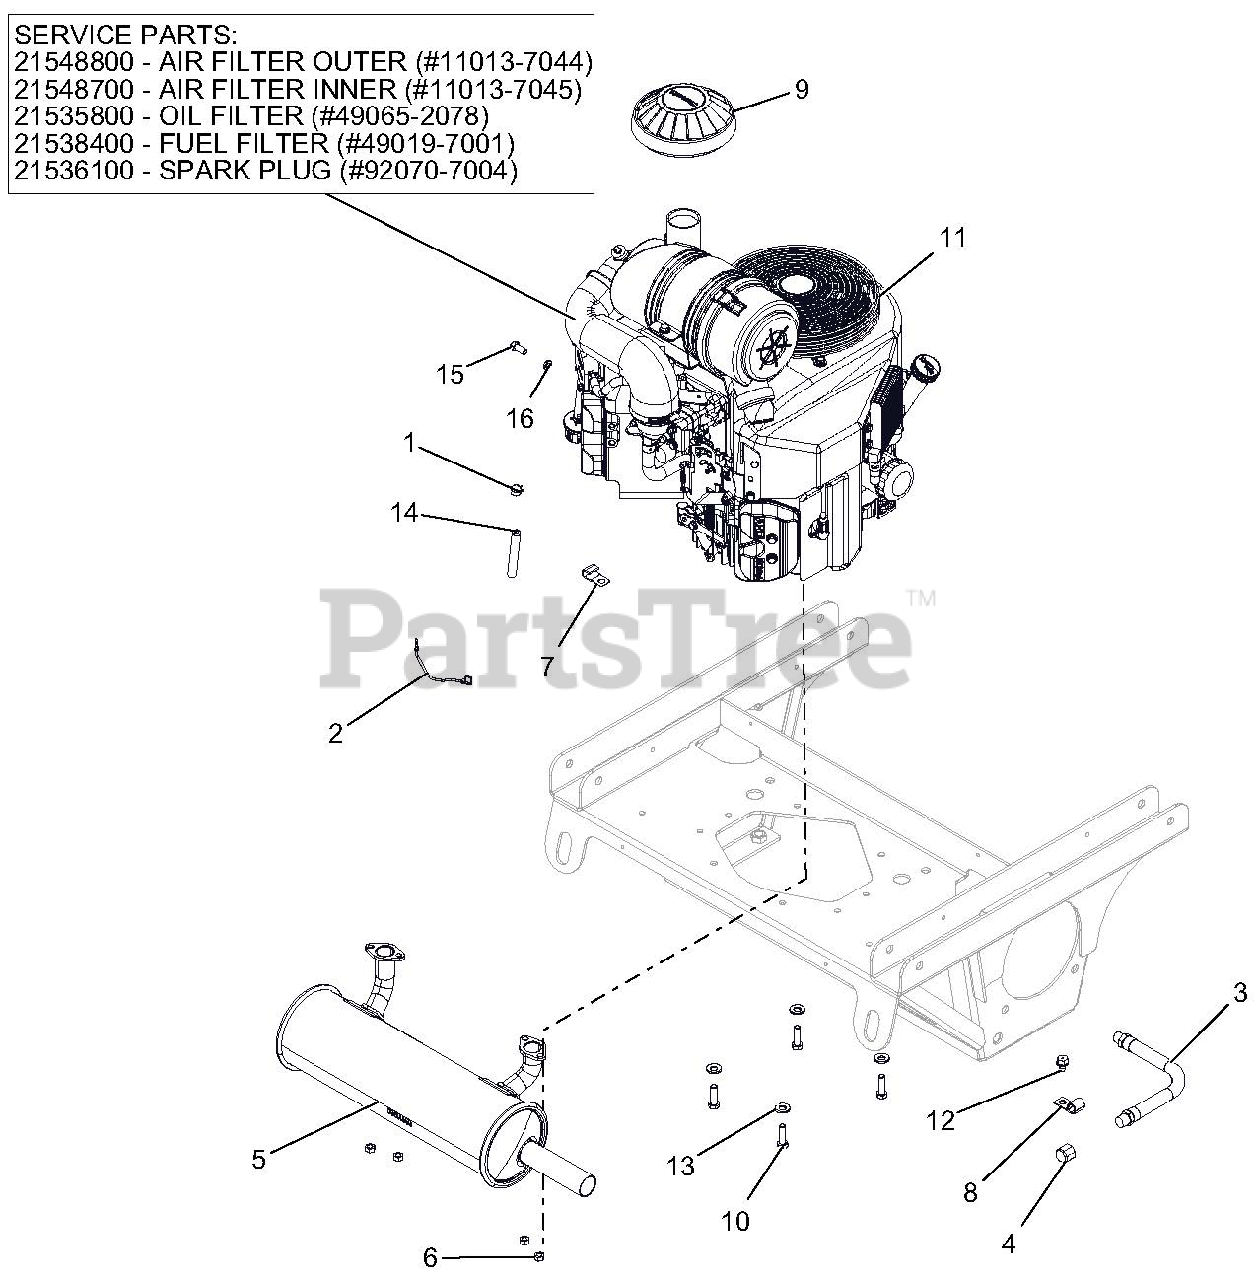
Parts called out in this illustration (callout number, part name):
1	CLAMP, FUEL LINE
2	LEAD - STARTER SOLENOID
3	HOSE, HYD .38-11-0K M6N0-M6NO
4	PIPE, CAP 3/8 NPT FEMALE
5	MUFFLER, 27-31 FX KAW
6	NUT-LK-TOP M8-1.25 YWZC
7	CLAMP, J
9	CAP, AIR CLEANER INTAKE (2")
10	BLT-HEX .38-16X1.25 GR5 YWZC NYTORQ
11	ENGINE, KAWASAKI FX850
11	AIR FILTER OUTER (#11013-7044)
11	AIR FILTER INNER (#11013-7045)
11	OIL FILTER (#49065-2078)
11	FUEL FILTER (#49019-7001)
11	SPARK PLUG (#92070-7004)
12	SCR-TAP .38-16X.50 HWH TR YWZ
13	WSHR, 3/8" SPRING DISC
14	.25 LOW-PERM GAS HOSE 18.00" LG - Valve to engine
15	@BLT-HEX M8-1.25X20 YWZC
16	WSHR-LK .31X.078 REG YWZC
